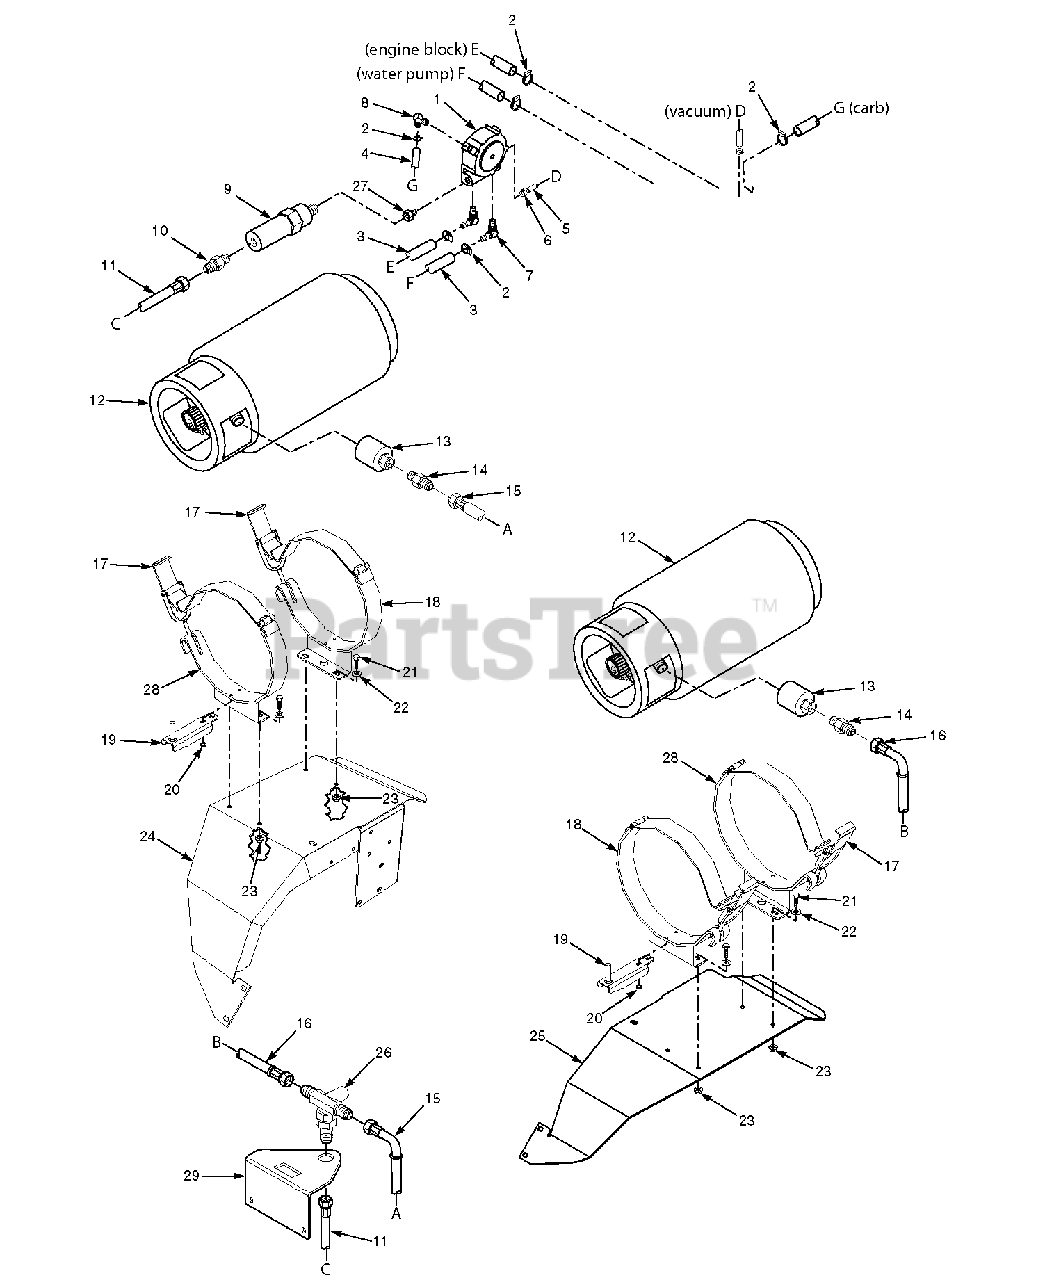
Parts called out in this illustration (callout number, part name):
1	Regulator, Kubota
2	Clamp, 0.87 Max. Dia.
3	Hose, 3/8" ID 300 PSI
4	Hose, LP
5	Hose, Vacuum Line
6	Clamp, 3/16" Hose ID
7	Fitting, 90 Degree - Kubota
8	Fitting, 90 Degree - Kubota
9	Lockoff Valve LP, Electric
10	Fitting, Union 3/8" Flare x 1/4" Pipe
11	LP Fuel Line, 45-1/2"
12	LP Fuel Tank
13	LP Quick Coupler
14	Fitting, Union 3/8" Flare x 1/4" Pipe
15	LP Fuel Line, 26-1/2"
16	LP Fuel Line, 52"
17	LP Tank Lock Bracket
18	Front LP Tank Mounting Bracket
19	LP Tank Locating Bracket
20	Bolt
21	Bolt, Hex Head 3/8-16 x 1"
22	Flatwasher, 3/8-.391 x .938 x .105
23	Nut, Serrated Flange 3/8-16
24	Fender Weldment, RH
25	Fender Weldment, LH
26	T-Connector, w/check valves
27	Fitting, Kubota
28	Rear LP Tank Mounting Bracket
29	Mounting Bracket, Tee Fitting and Selector Switch
